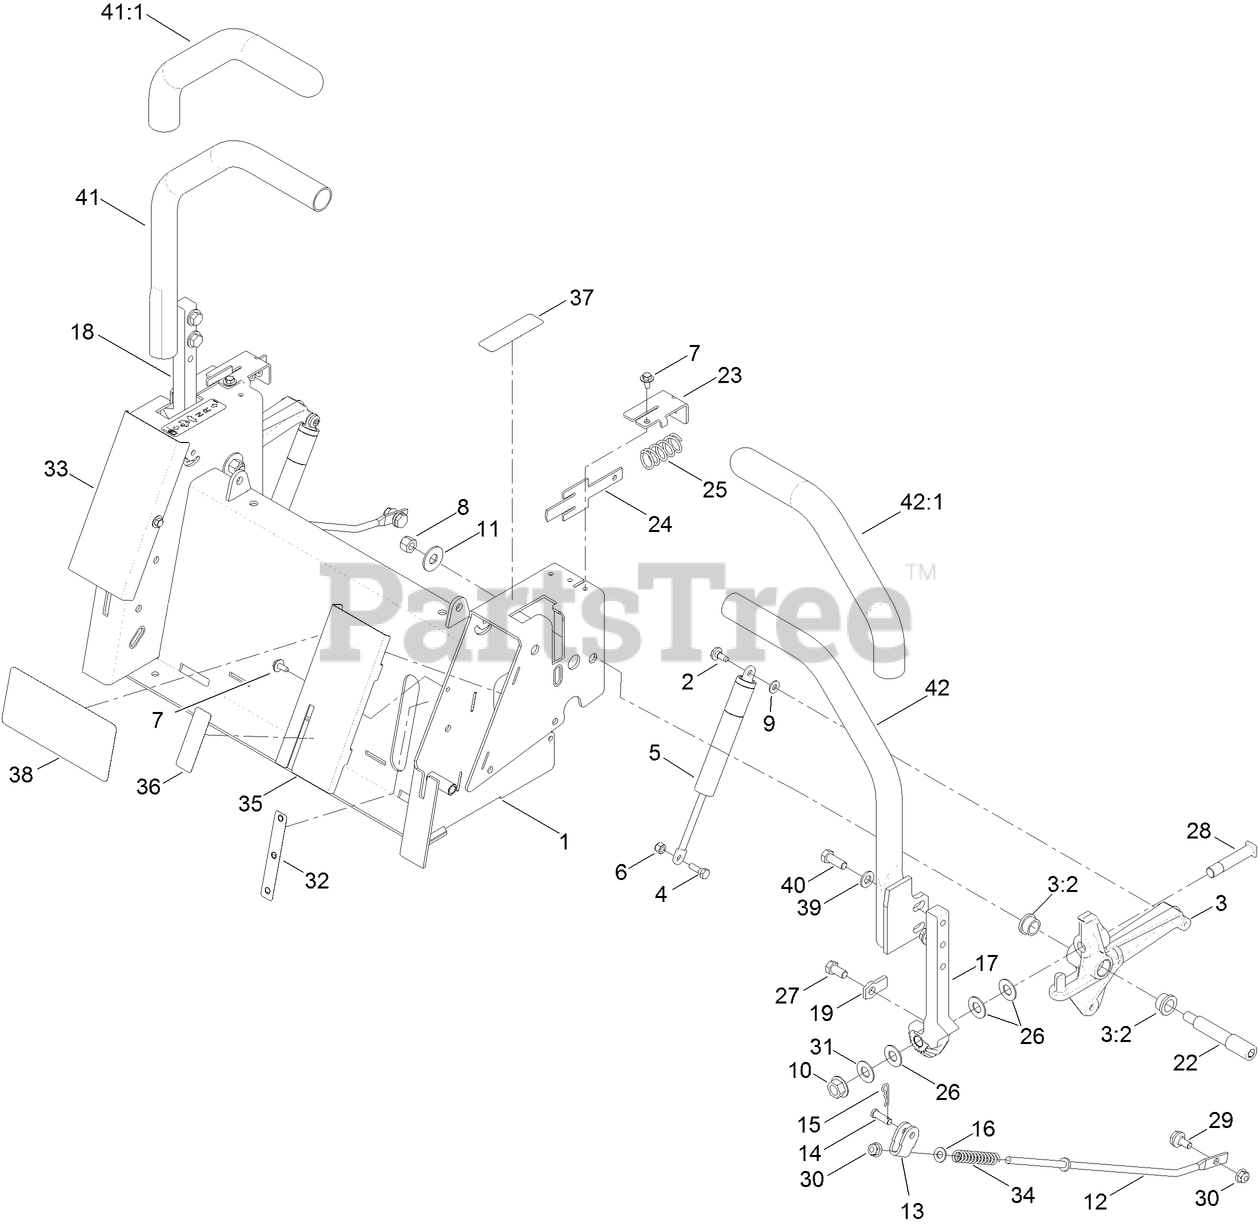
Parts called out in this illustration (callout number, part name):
1	BOX-CONTROL
2	SCREW-SHOULDER
3	ACTIVATOR ARM ASM
3:2	BUSHING
4	BOLT-SHOULDER
5	DAMPER-CONTROL, MOTION
6	NUT-LOCK, NI
7	SCREW-HHFTF
8	NUT-LOCK, NI
9	WASHER
10	NUT-HF
11	WASHER-FLAT
12	ROD-CONTROL
13	BRACKET-CONTROL
14	PIN-CLEVIS
15	PIN-COTTER
16	WASHER-PLAIN
17	ARM-ACTUATOR, LH
18	ARM-ACTUATOR, RH
19	TAB-STOP
22	BOLT-SHOULDER
23	BRACKET-RETURN
24	PLATE-RETURN
25	SPRING-COMPRESSION
26	WASHER-PIVOT
27	SCREW-HH
28	BOLT-SHOULDER
29	BOLT-SHOULDER,HFH
30	NUT-HF, NI
31	WASHER-TEFLON
32	DECAL-FILL, FUEL
33	COVER-CONTROL, RH
34	SPRING-RETURN, NEUTRAL
35	COVER-CONTROL, LH
36	DECAL-BRAKE, PARKING
37	DECAL-CONTROL, MOTION
39	WASHER-FLAT
40	SCREW-HH
41	RH LEVER/GRIP ASM
41:1	GRIP-CONTROL, MOTION
42	LH LEVER/GRIP ASM
42:1	GRIP-CONTROL, MOTION
